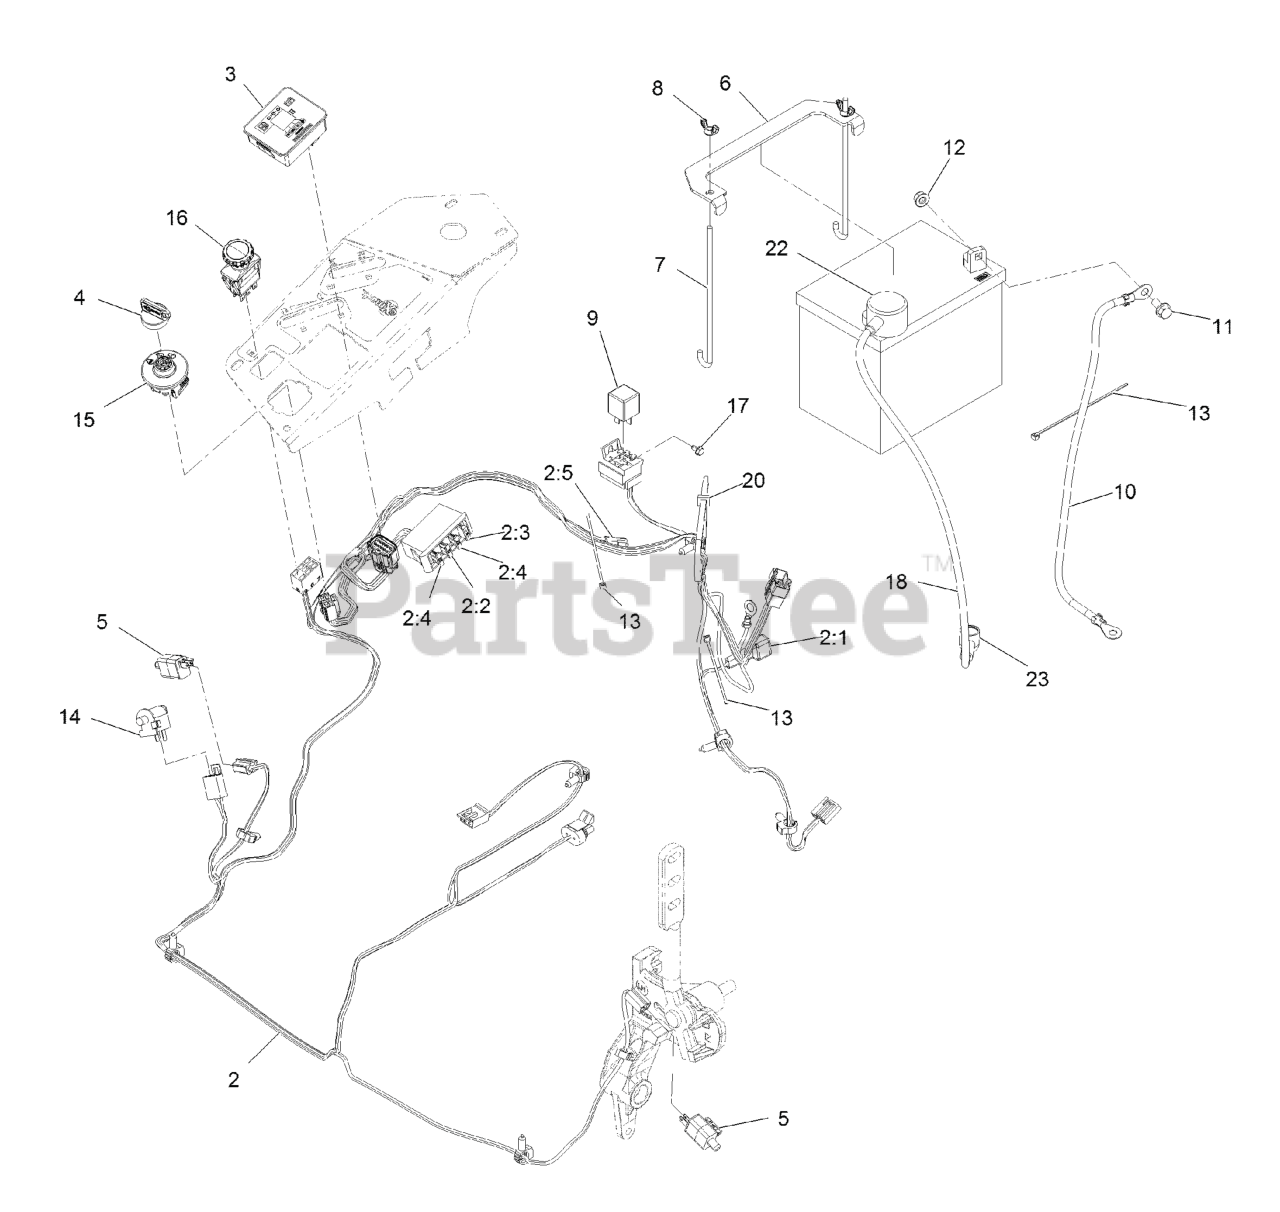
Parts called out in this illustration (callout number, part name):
2	HARNESS-WIRE, MAIN
2:2	FUSE-BLADE, 10 AMP
2:3	FUSE-BLADE, 15 AMP
2:4	FUSE-BLADE, 25 AMP
2:5	CAP-PLUG
3	FUEL/HOUR METER ASM
4	KEYS-IGNITION (SPARE PAIR
4	KEY-IGNITION
6	STRAP-TIE DOWN, BATTERY
7	BOLT-HOLDDOWN
8	WINGNUT
10	CABLE-BATTERY, NEGATIVE
11	SCREW-HHF
12	NUT-HF, NI
13	TIE-CABLE
14	SWITCH-BAIL
15	SWITCH-IGNITION
16	SWITCH-PTO, 10 AMP
17	SCREW-HWH
18	CABLE-BATTERY, POSITIVE
19	WASHER-FLAT
20	TIE-PLASTIC
22	INDICATOR-LED, RED
23	HARNESS-LIGHT, INDICATOR
24	CLAMP-HOSE
25	INSULATOR-BATTERY
26	INSULATOR-SOLENOID
